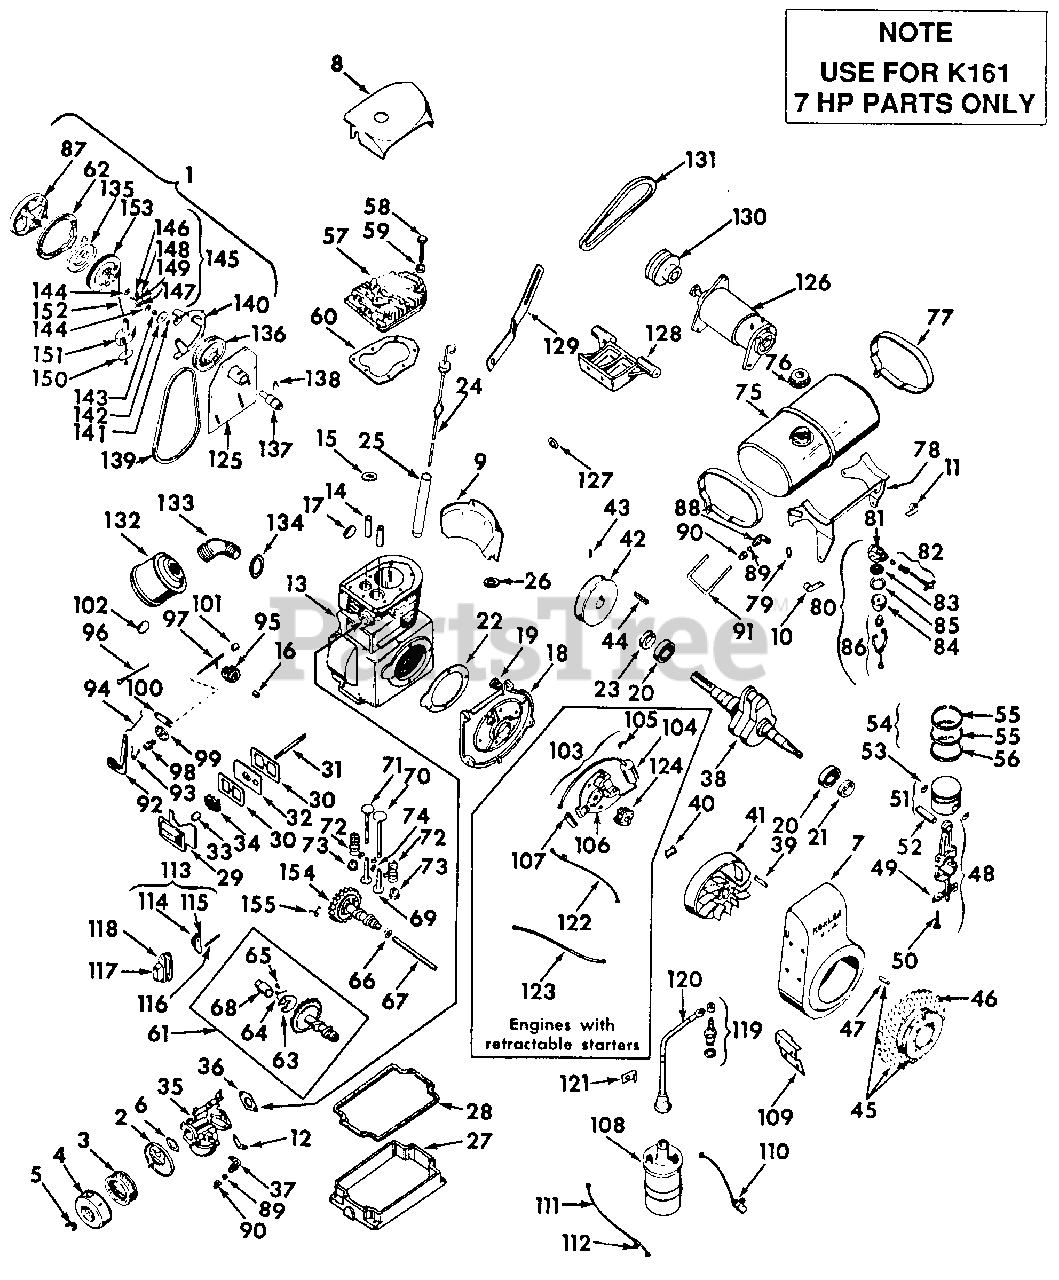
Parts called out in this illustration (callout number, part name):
1	Starter Assy, Retractable
2	Base, Air Cleaner
3	Element, Air Cleaner Filter
4	Cover, Air Cleaner
5	Nut, Air Cleaner Wing
6	Gasket, Air Cleaner
7	Housing Assembly, Blower
8	Baffle, Cylinder Head Air
9	Baffle, Cylinder Air
10	Clip, Cable Harness
11	Clip, Choke Cable
12	Bracket, Choke
13	Crankcase Assy
14	Guide, Valve
15	Insert, Exhaust Valve
16	Shaft, Governor
17	Plug, 1-1/8 Expansion
18	Plate, Crankcase Brg
19	Plug, 5/8 Button
20	Bearing, Crankcase Ball
21	Seal, Crankcase Brg Plate Oil
22	Gasket, Brg Plate
23	Seal, Crankcase Oil
25	Tube, Oil Fill
26	Insert, Intake Valve
27	Base, Oil Pan
28	Gasket, Oil Pan Base
29	Cover w/Filter, Breather
30	Gasket, Breather
31	Stud, Breather Cover
32	Plate Assembly, Breather
33	Seal, Breather
34	Filter, Breather
35	Carburetor Assy
36	Gasket, Carburetor
37	Elbow, Carburetor to Fuel Line
38	Crankshaft
39	Key, Crankshaft
40	Washer, Flywheel Tension
42	Pulley w/Clutch Drive Plate, Flywheel
43	Screw, Flywheel Pulley Set
44	Key, 1/4 X 7/8 Sq Parallel
45	Cup Assy, Flywheel Drive
46	Screen, Drive Cup Grass
47	Pin, Flywheel Drive Cup
48	Rod Assy, Connecting, Std
49	Lock, Connecting Rod Screw
50	Screw, Connecting Rod
51	Piston Assy, Std
52	Pin, Piston, Std
53	Retainer, Piston Pin
54	Ring Set, Piston, Std
55	Ring, Compression
56	Ring, Oil Control
57	Head, Cylinder
58	Screw, Cylinder Head
59	Washer, Cylinder Head
60	Gasket, Cylinder Head
61	Camshaft Assy
62	Flange, Intermediate
63	Flyweight, Camshaft
64	Spring, Spark Advance
65	Pin, Camshaft Flyweight
66	Shim, Camshaft, .005
67	Pin, Camshaft
68	Cam, Ignition
69	Tappet, Valve
70	Valve, Intake
71	Valve, Exhaust
72	Spring, Valve
73	Retainer, Valve Spring
75	Tank Assy, Fuel w/Filler Cap
78	Bracket Assy, Fuel Tank
80	Filter
86	Bail Assy, Fuel Filter Bowl
88	Connector
89	Sleeve
91	Line, Fuel Filter to Carburetor Fuel
93	Spring, Governor
96	Pin
98	Bushing, Cross Shaft
101	Bearing, Cross Shaft Needle
108	Coil, Ignition
110	Condenser
111	Cable Assy, Condenser to Breaker
114	Set
115	Bracket, Point Breaker
116	Rod, Breaker
117	Cover
118	Gasket
119	Plug
120	Kit, Lead
123	Sleeve, Ground Cable
126	Motor Generator
130	Pulley, Motor Generator Drive
132	Muffler
133	Elbow, Exhaust Muffler
137	Bearing, Retractable Starter Ball
138	Retainer, Retractable Starter Ball Brg
145	Shoe Assembly
149	Lever, Friction Shoe Brake
154	Camshaft Assy
